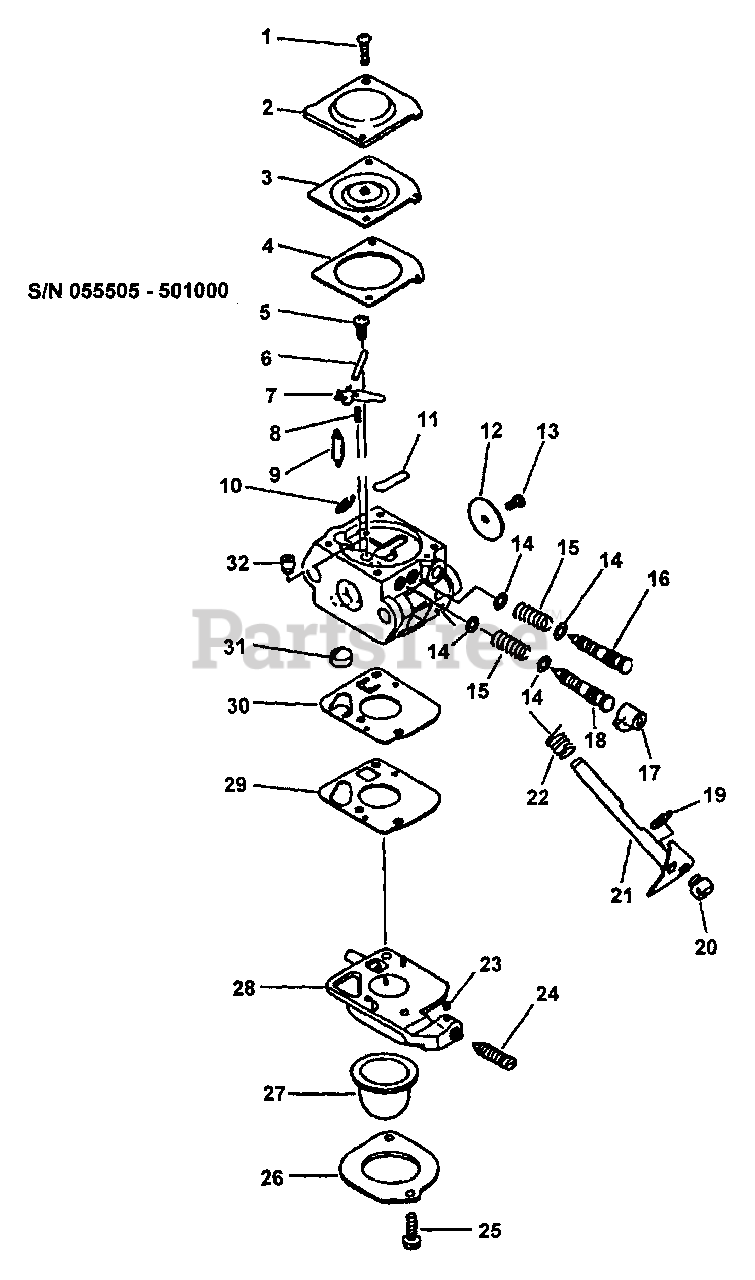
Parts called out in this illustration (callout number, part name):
2	COVER, METERING DIAPHRAGM
3	DIAPHRAGM, METERING
4	GASKET, METERING
6	PIN, METERING LEVER
7	LEVER, METERING
8	SPRING, METERING LEVER
9	VALVE, NEEDLE
11	PLUG, WELCH
12	VALVE, THROTTLE
15	SPRING, NEEDLE
16	NEEDLE, IDLE
17	CAP, LIMITER - RED
18	NEEDLE, HIGH SPEED
21	SHAFT, THROTTLE
22	SPRING, THROTTLE RETURN
23	PIECE, FRICTION
24	SCREW, IDLE ADJUST
26	RETAINER
27	BULB, PURGE
28	BODY ASSY, PURGE
31	STRAINER
32	NOZZLE, CHECK VALVE
